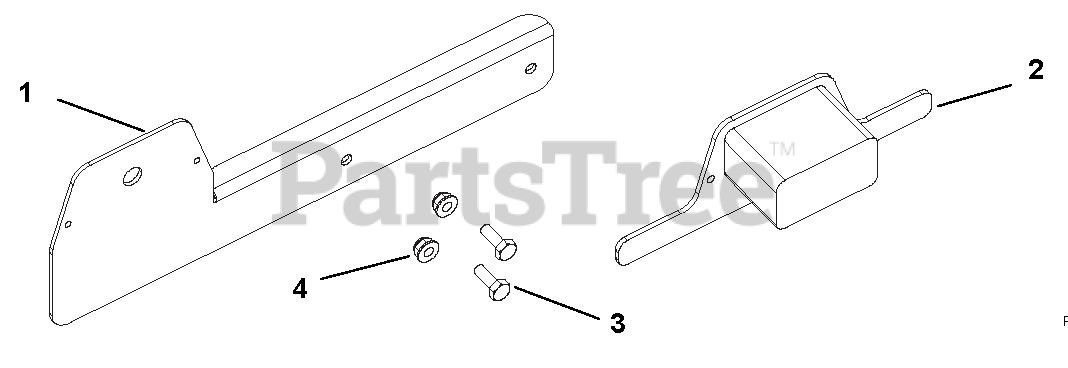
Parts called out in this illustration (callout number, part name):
1	WLDMT, LOG CRADLE
2	@BLT-HEX .38-16X1.25 GR5 YWZC
3	@NUT-LK-TOP-FLG .38-16 YWZC
